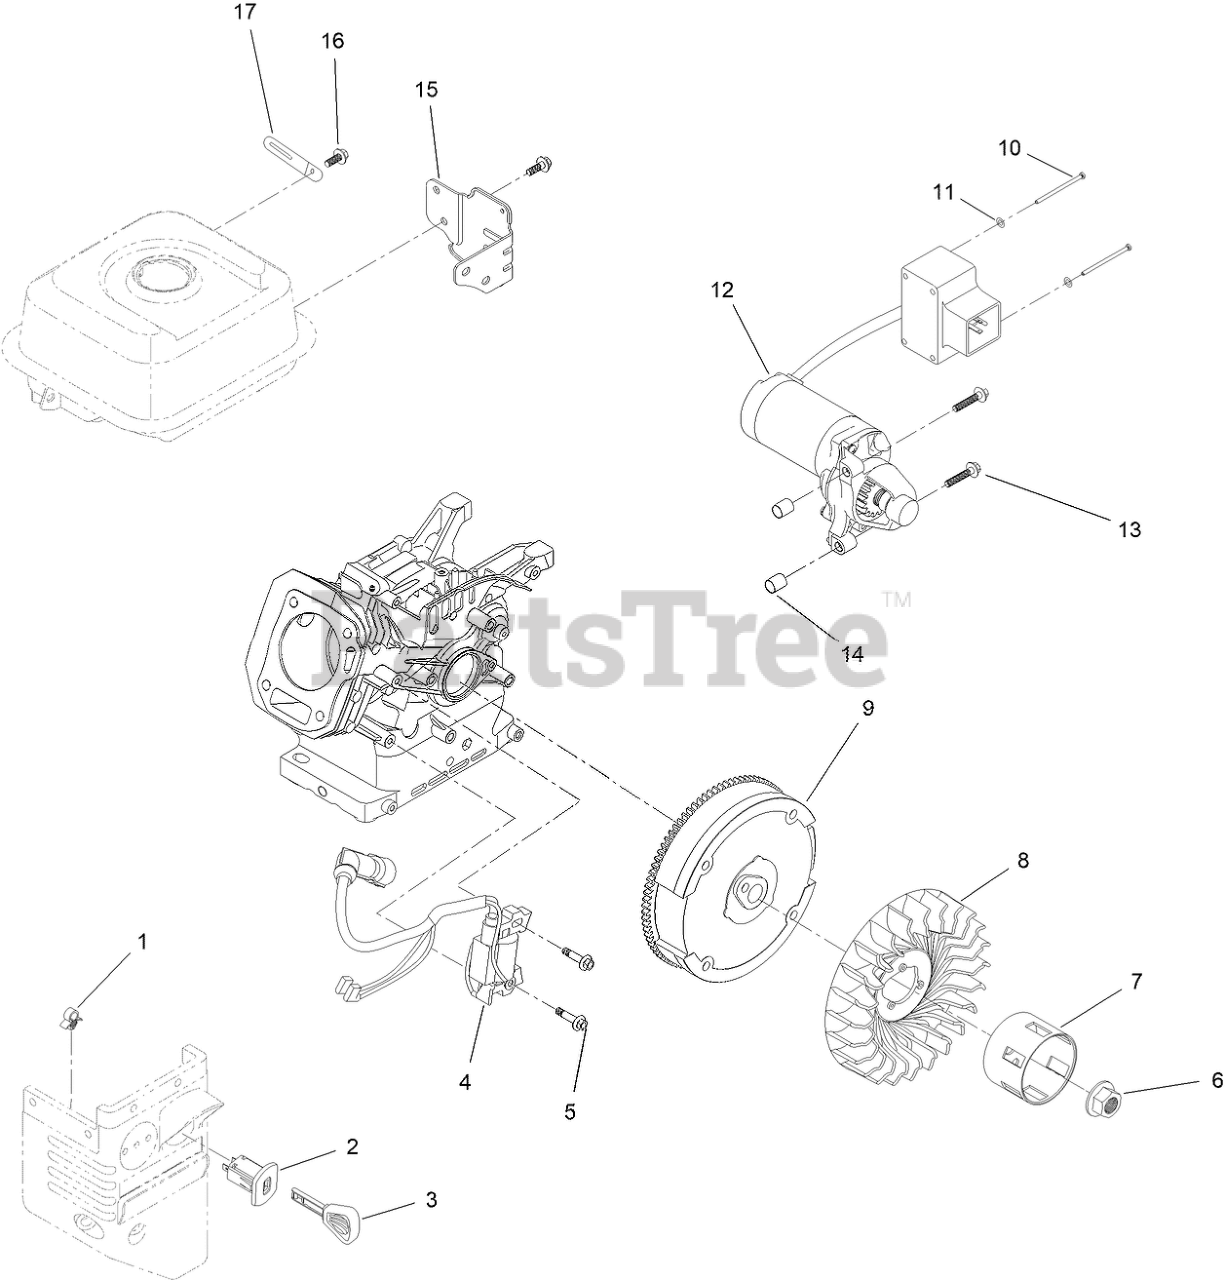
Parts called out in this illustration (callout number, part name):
2	SWITCH-KEY
4	IGNITION COIL ASM
5	SCREW-HHF
6	NUT-FLANGE
7	CUP-STARTER
9	FLYWHEEL
10	SCREW-BHP
11	WASHER-PLAIN
12	MOTOR-STARTER
13	SCREW-FLANGE
14	PIN-DOWEL
15	BRACKET-BOX, SWITCH
16	SCREW-HHF
17	CLIP-HARNESS, WIRE
